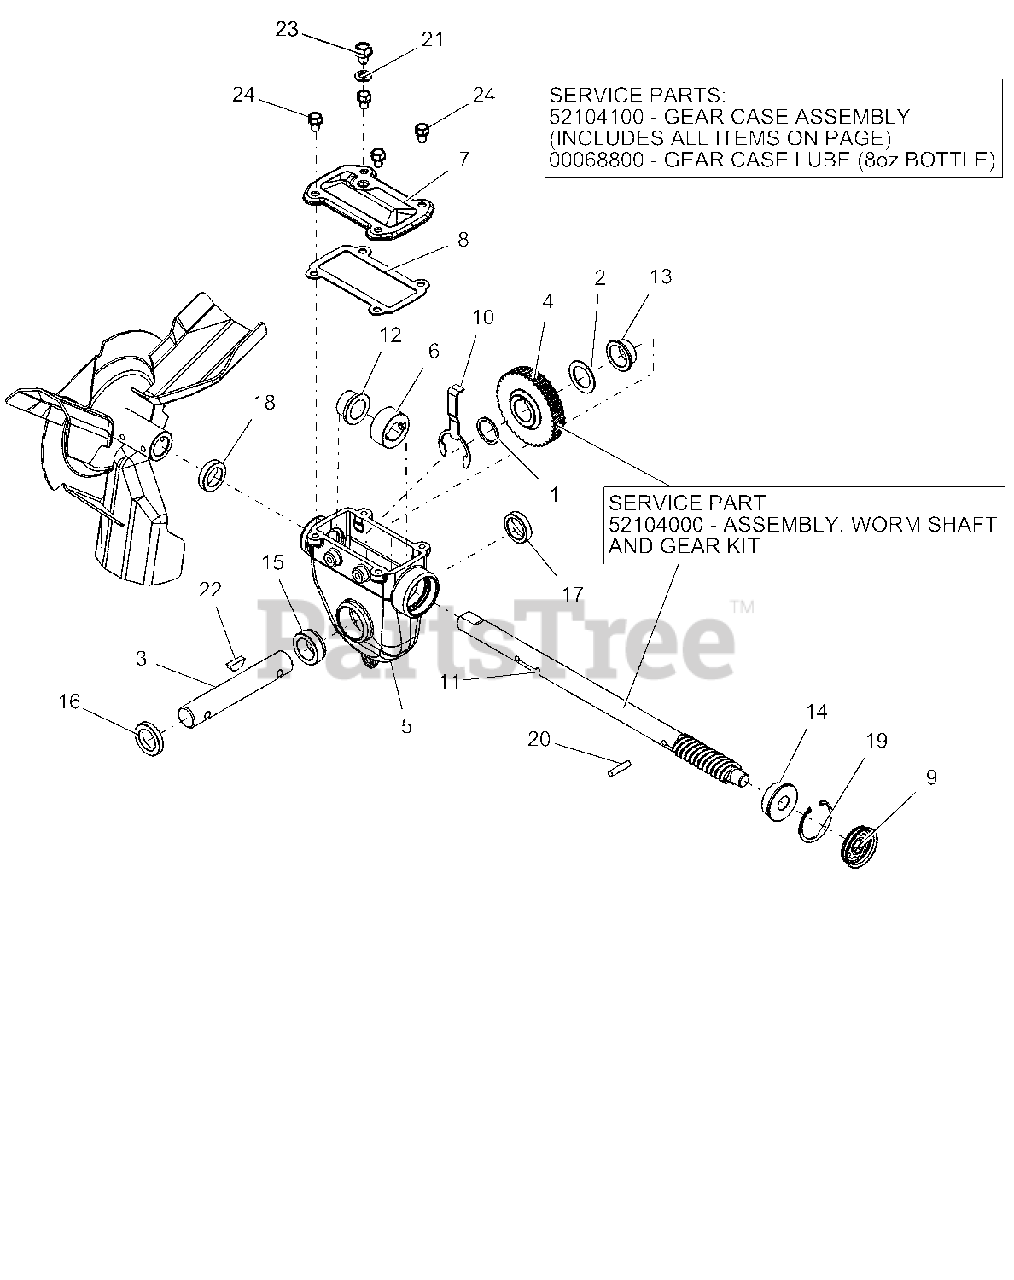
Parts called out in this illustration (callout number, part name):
1	WSHR-FL-STL 1.010X1.250X.068YZ
2	WSHR-FL-STL 1.010X1.505X.062YZ
3	RAKE SHAFT, SHORT-COMMON
4	WORM GEAR
5	GEARCASE, LARGE MACHINED
6	THRUST COLLAR, .875"ID SLIPFIT
7	COVER, TOP - LARGE IRON
8	GASKET, TOP - LARGE GEARCASE
9	COVER, GEAR CASE 1.75"
10	BUSHING RETAINER, LARGE
11	WORM SHAFT & GEAR
11	SHAFT, WORM - DELUXE
12	BSHG-FLG .879X1.128X.75X1.45
13	BSHG-FLG 1.006X1.128X.555X1.45
14	BSHG-FLG .628X1.503X.58X1.725
15	BSHG-FLG LARGE, RIGHT
16	SEAL-OIL .999X1.500X.250 TBC29
17	SEAL-OIL .999X1.375X.312 TBC29
18	SEAL-OIL .873X1.375X.312 TBC29
19	RG-RTNG-INT 1.750X.062
20	PIN-STR .250X1.12 6150
21	WSHR-BND-SEAL .38X.75X.11 GALV
22	KEY-WDRF .25X.875 HRD #A
23	@SCR-ROLOK .38-16X.50 HWH YWZC
24	BOLT, SEMS .31-18X.50 GR5 YWZC
25	GEAR CASE ASSY - DLX IRON
26	ARIENS L3 LUBE, 8 OZ BOTTLE
